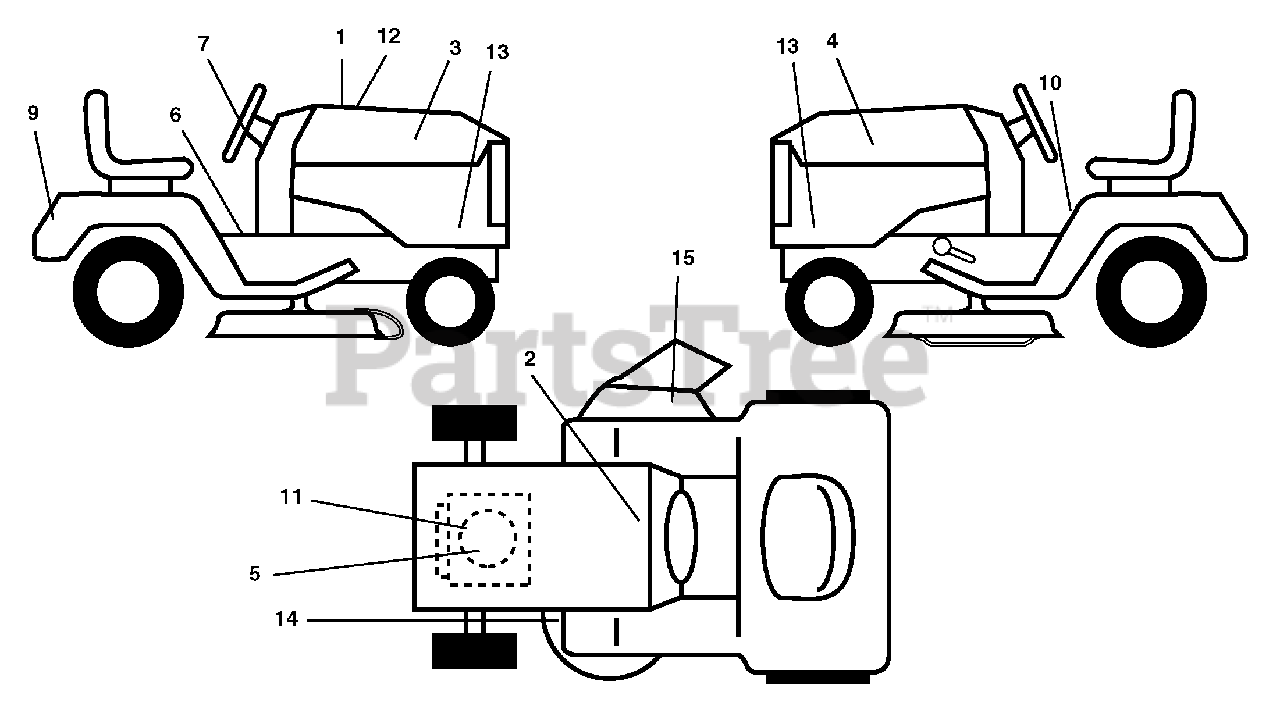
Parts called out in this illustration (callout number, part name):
1	Decal Hood Cust. Resp.
2	Decal Battery
3	Decal Hood RH
4	Decal Hood LH
5	Decal Engine Husq. Logo
6	Decal Fender Oper
7	Decal Wheel Steering
9	Decal Fender Husq
10	Decal Fender Danger E/F
11	Decal Engine
12	Decal Hood Replacement
13	Decal Hoodsides
14	Decal V-Belt Schematic
15	Decal Deck B 42
